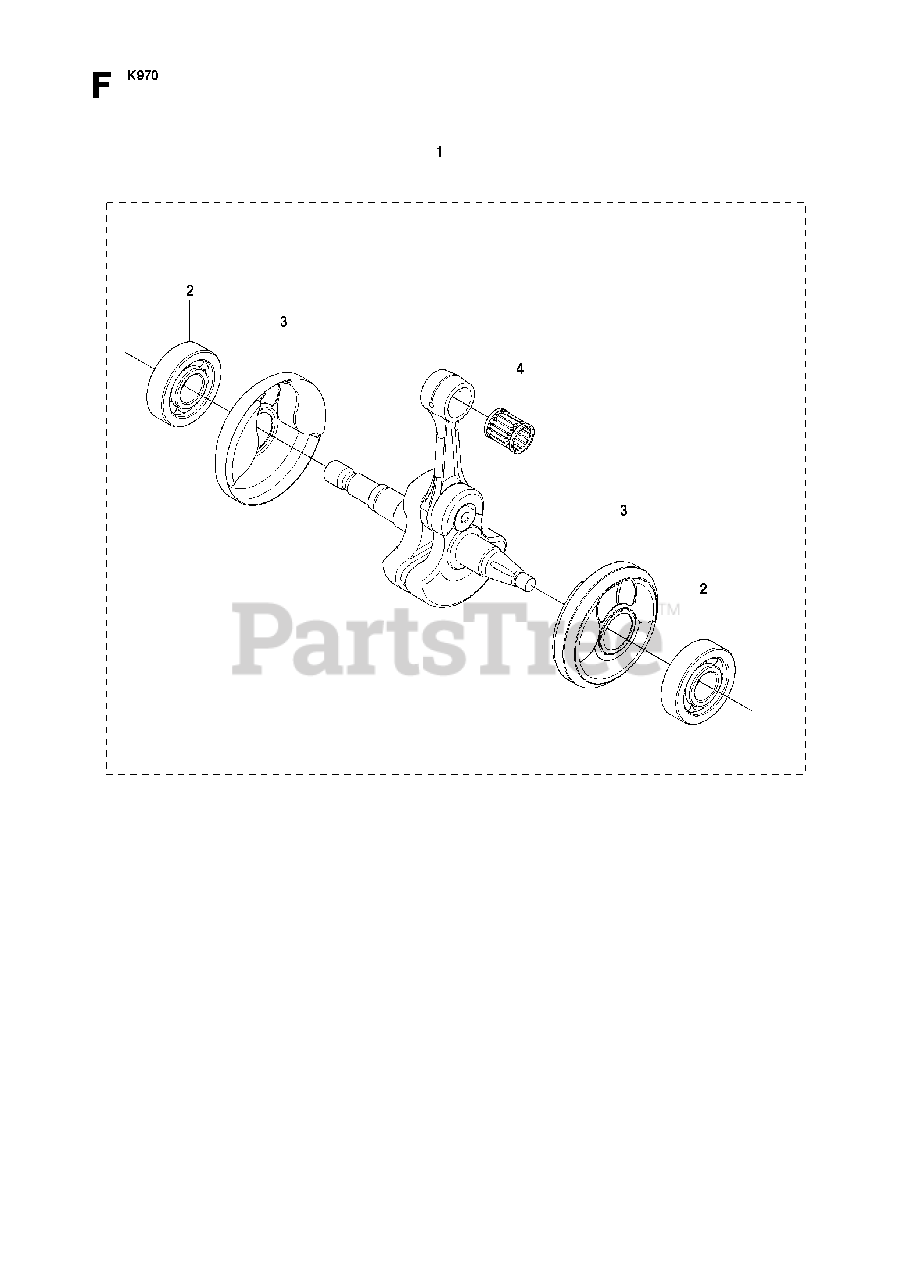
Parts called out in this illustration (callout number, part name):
1	CRANKSHAFT ASSY
2	BALL BEARING
4	NEEDLE BEARING
